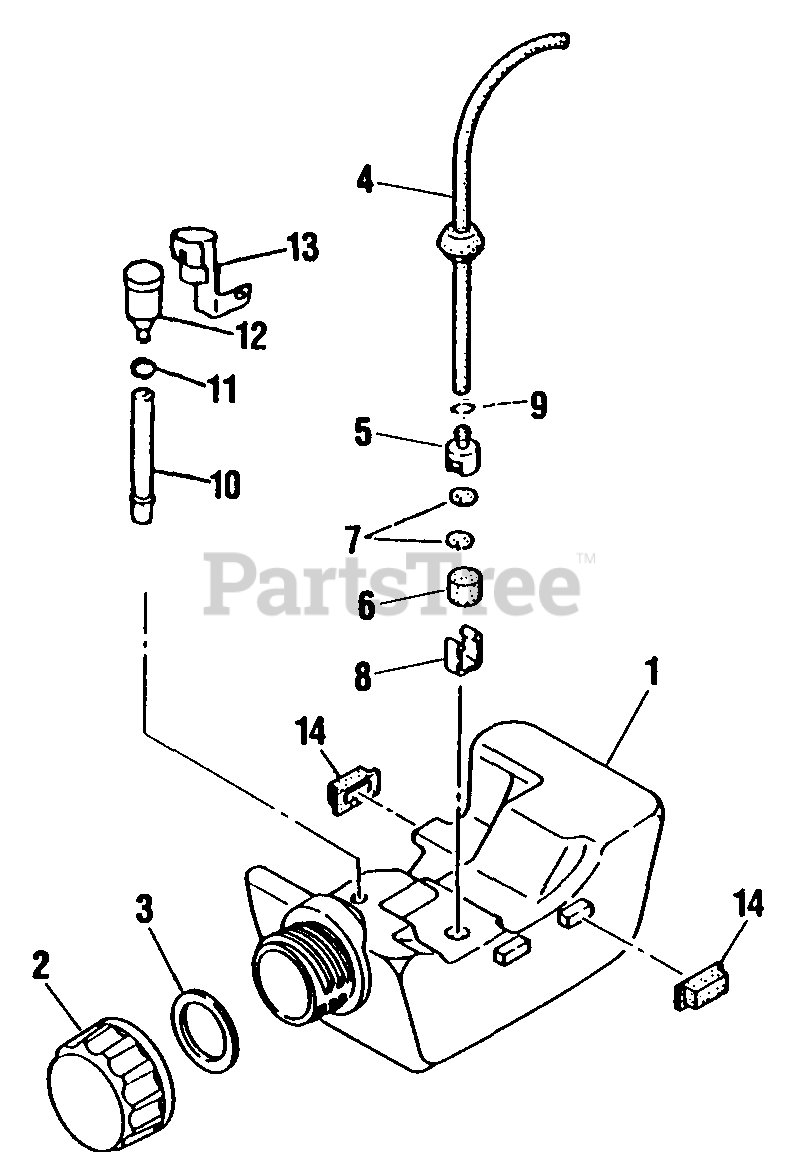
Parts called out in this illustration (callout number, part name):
1	TANK, FUEL
2	CAP, FUEL
3	GASKET, CAP
4	PIPE - FUEL
5	WEIGHT, FUEL FILTER
6	ELEMENT, FILTER - LARGE
7	STRAINER - SMALL
9	RING, RETAINING - 6
10	PIPE - BREATHER
11	RING, RETAINING - 6
12	VALVE
14	CUSHION, TANK
